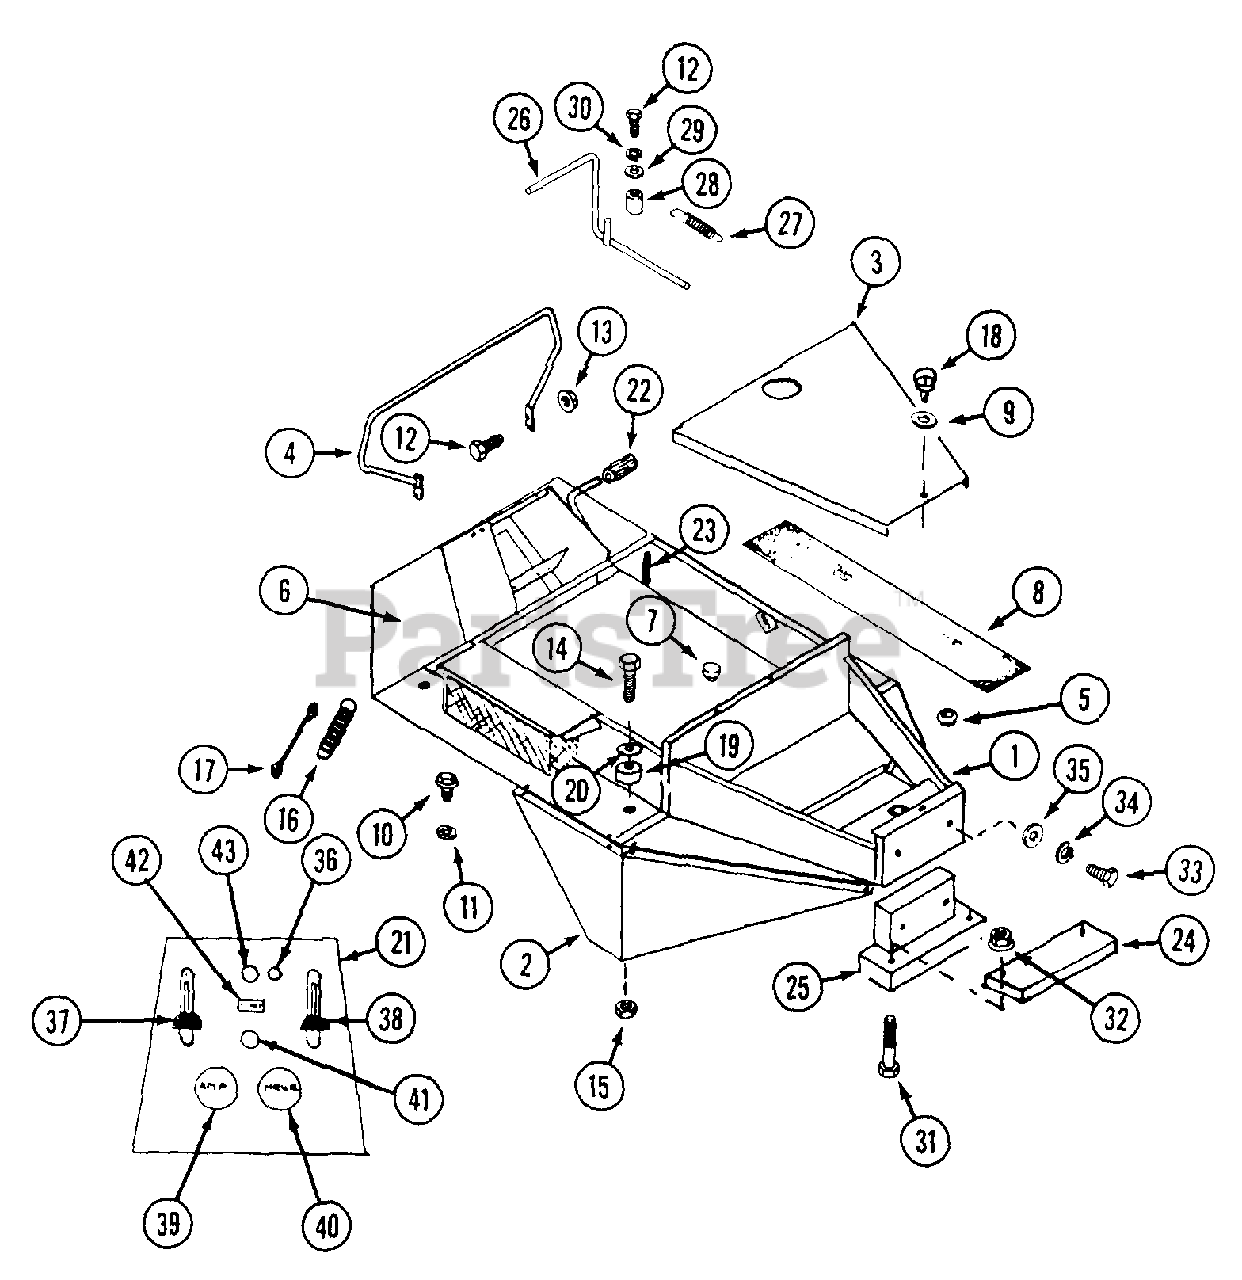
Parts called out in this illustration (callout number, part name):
1	BODY
2	FENDER - L.H.
6	PAD - safety walk L.H. front
6	PAD - safety walk R.H. front
7	BUMPER - nylon
8	PAD - safety walk R.H. side
9	GROMMET
10	BOLT - 1/4"-20 x 3/4" tapping
11	LOCKWASHER - 1/4"
12	BOLT - 5/16"-18 x 3/4"
13	NUT - 5/16"-18 flange lock
14	BOLT - 1/2"-13 x 3"
15	NUT - 1/2"-13 lock
17	DECK LIFT CABLE
19	RUBBER BODY MOUNT
20	BODY MOUNT WASHER
22	BRAKE PEDAL PAD
24	TAIL WEIGHT - 13 lbs.
26	LEVER - brake lock
27	SPRING - return
29	WASHER - 5/16"
30	LOCKWASHER - 5/16"
31	BOLT - 3/8"-16 x 4-1/2"
32	NUT - 3/8"-16 flange lock
33	BOLT - 5/16"-18 x 1"
34	LOCKWASHER - 5/16"
35	WASHER - 5/16"
